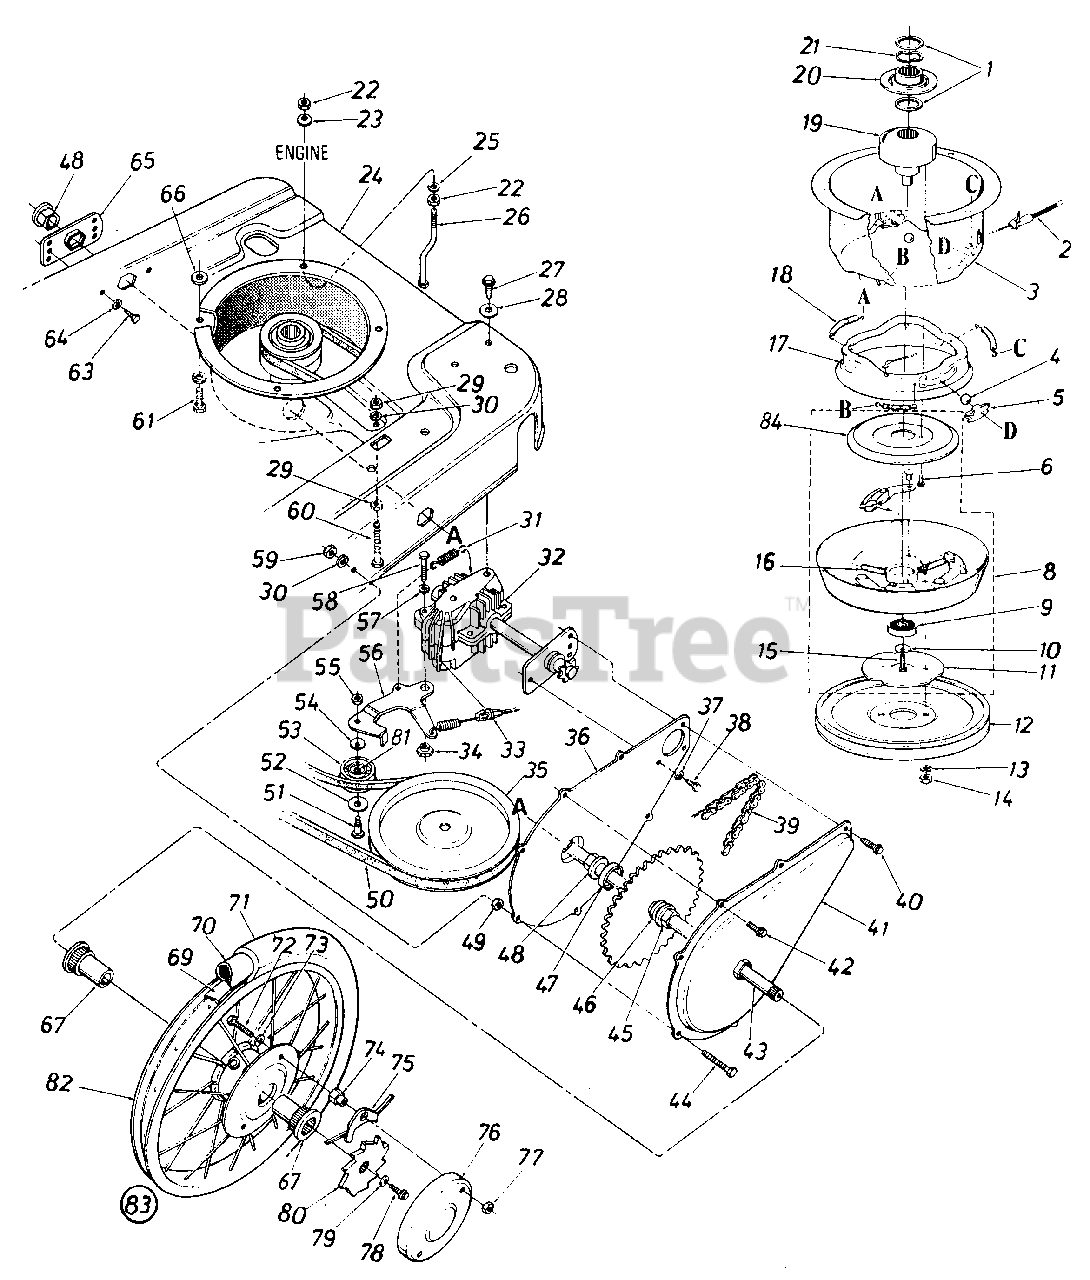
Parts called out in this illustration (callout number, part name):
1	WASHER-SERRATED
2	CABLE-CLUTCH
3	HOUSING-CLUTCH
4	BALL-STEEL
5	BALL-BLOCK
6	SCREW-HEX WASH SF TAPP
8	HOUSING-CLUTCH MBC
9	BEARING-BALL
10	WASHER-BELL
11	HOUSING ASSY-W/FPA
12	PULLEY-5/8-V
13	WASHER-LOCK-3/8
14	NUT-HEX 3/8-24
15	SCREW-HEX 7/16 N.F. X 2 GR.5
16	SPRING-COMPRESSION
17	CONE-BRAKE CUP
18	SPRING-EXTENSION
19	ADAPTER-FIXED PULLEY
20	PULLEY-MOVABLE
21	WASHER-WAVE
22	NUT-HEX 5/16-18
23	WASHER-BELL .337 X .867 X .057
24	FRAME-HI WHEEL
25	WASHER-LOCK-5/16
26	GUARD-BELT-5/16 BOLT
27	SCREW-HEX WASH HD 5/16-18X1/2
28	WASHER-BELL .3/8ID X 1.12OD X .030
29	NUT-HEX 1/4-20
30	LOCK WASHER 1/4 DIA
31	SPRING-EXTENSION
32	TRANSMISSION-COMP
33	CABLE-CLUTCH X 50.0
34	SPACER-SHLD
35	PULLEY
36	COVER-CHAIN-45T
37	LOCK WASHER 1/4 DIA
38	SCREW-HEX B-TAP 1/4 X .38
39	#48 CHAIN 1/2 PITCH X 51 LINKS
40	SCREW-HEX WASH SF TAPP
41	CASE-CHAIN-45T
42	SCREW-HEX B-TAP 1/4 X .38
43	AXLE ASSY-RR
44	SCREW-HEX 1/4-28 X .88
45	BEARING-HEX FLANGE
46	WASHER-FL-.640 ID X .94 OD
47	SPACER-.630 X 1.250 OD
48	BEARING-HEX FLANGE
49	NUT-HEX JAM 1/4-28
50	BELT-V- 3/8 X 28
51	SCREW-SHLD
52	WASHER-FL .995 X .032
53	KIT-PULLEY
54	WASHER-SPRING BELL
55	NUT-HEX 1/4-28
56	BRACKET ASSY-IDLER
57	LOCK WASHER 1/4 DIA
58	SCREW-HEX 1/4-20 X 1.25
59	NUT-HEX 1/4-28
60	SCREW-HEX 1/4-20 X 2.00
61	SCREW-HEX
63	SCREW-HEX B-TAP 1/4 X .38
64	LOCK WASHER 1/4 DIA
65	BEARING-CUP HEX
66	WASHER-FL-.406 ID X .74 OD X .063
67	BEARING-FLANGE
69	RIM STRIP
70	TUBE-16 X 2.12
71	TIRE-16 X 2.125
72	SCREW-HEX 5/16-18 X 1.00
73	WASHER-INTERN L 5/16
74	NUT-HEX 5/16-18 SPEC
76	COVER-WHEEL
77	NUT-HEX 5/16-18
78	SCREW-TAP
79	WASHER-SPRING BELL
80	RACHET-WHEEL
81	BEARING-NEEDLE
82	WHEEL RIM 16.0 X 2.1
83	WHEEL ASSY W/TIRE 16 X 2.12
84	CONE-CLUTCH
